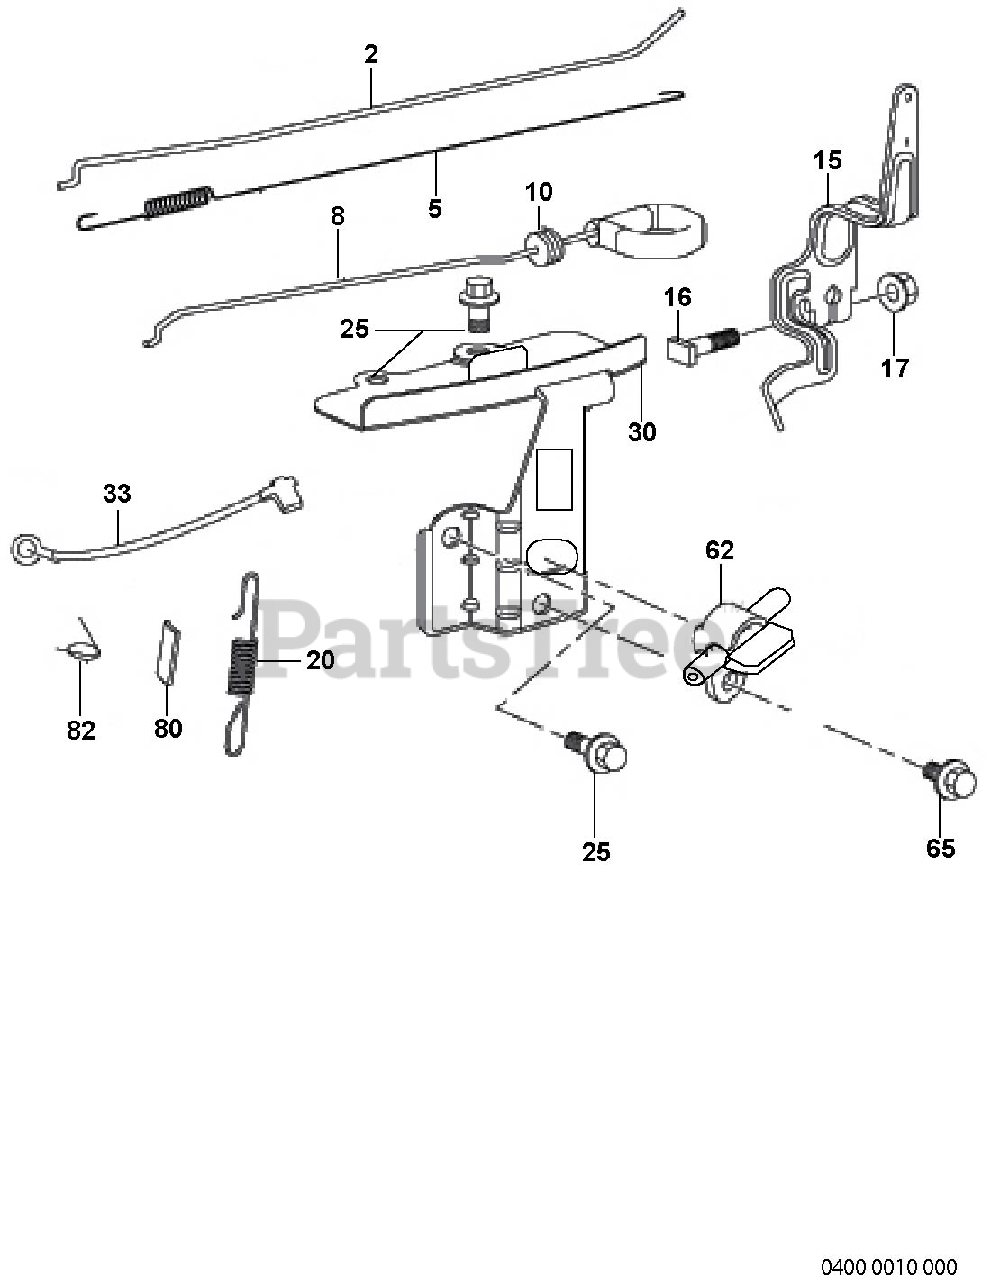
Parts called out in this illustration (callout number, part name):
400-2	THROTTLE CONTROL ROD
400-5	THROTTLE RETURNING SPRING
400-10	CHOKE LEVER HOLD
400-20	GOVERNOR SPRING
400-30	SPEED CONTROL BRACKET ASSY
400-62	FUEL VALVE
